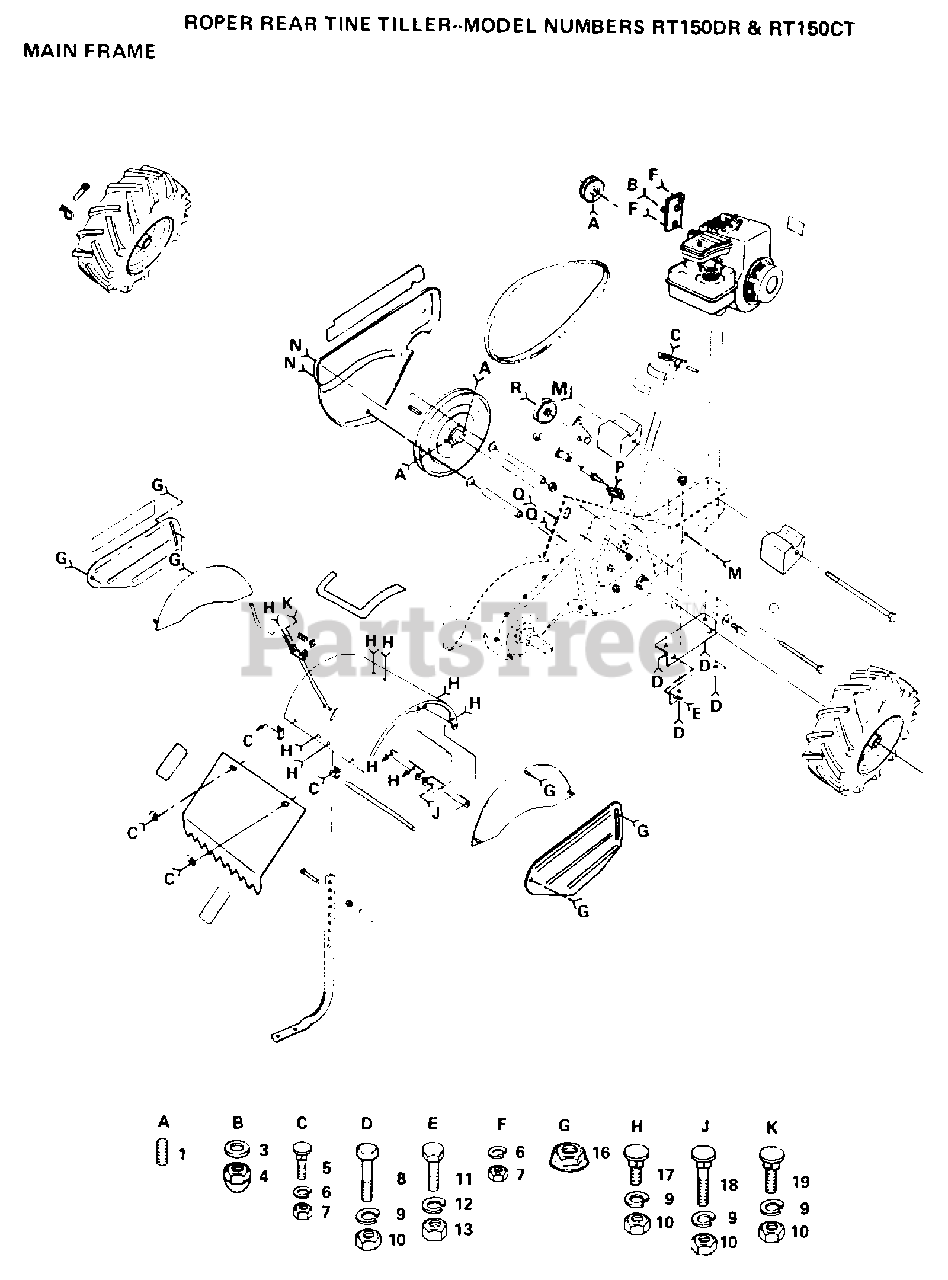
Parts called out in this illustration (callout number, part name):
1	SET SCREW
3	WASHER
4	NUT TI
5	BOLT
6	LOCKWASHER
8	BOLT.HEX.5/16-1.5
9	LOCKWASHER
10	NUT.HEX.5/16-18
11	BOLT
12	LOCKWASHER
13	NUT.HEX.3/8-16UNC
16	NUT
17	BOLT
18	BOLT CRT
19	BOLT
